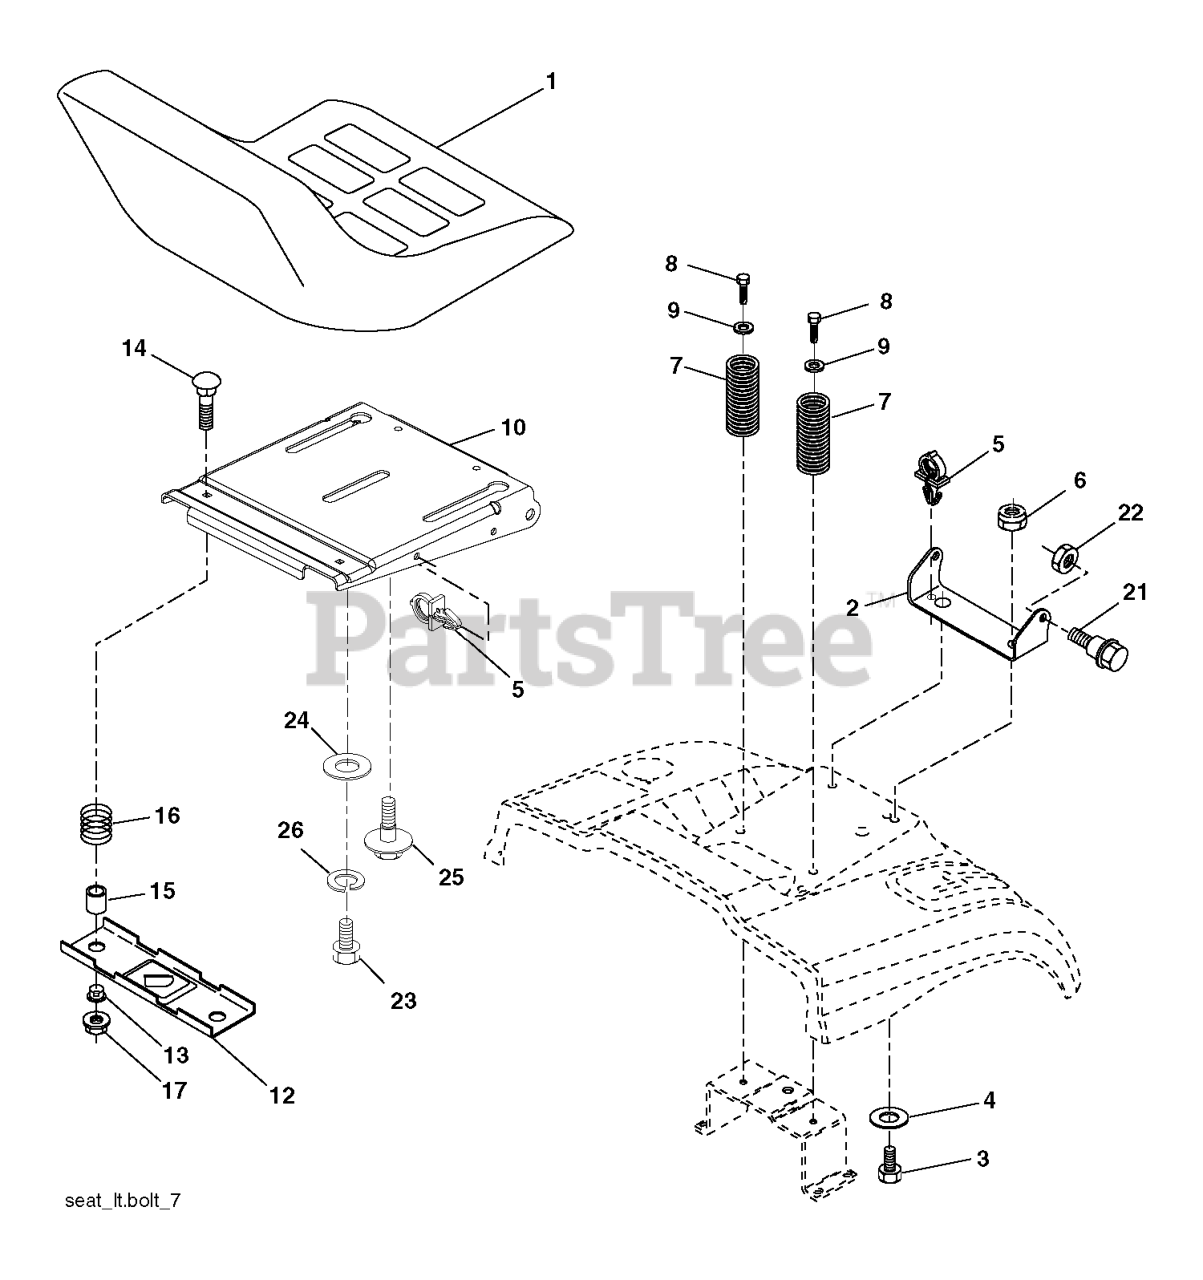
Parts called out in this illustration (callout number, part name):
1	SEAT.XG090.BLK.KB/BLT.NO-LOG
2	SEAT PIVOT BRKT
3	BOLT, HEX 3/8-16X1
6	NUT
7	SPRING COMPRESSION
8	SCREW 3/8-16X1
9	WASHER
10	PAN.ASM.SEAT.1SLOT
12	BRKT.MNTNG.SWITCH.SEAT.BLACK
14	BOLT.ROUND.HEAD.SQUARE.NECK
15	SPACER SPLIT 28X.96
17	NUT T
21	BOLT.SHOULDER.5/16-18
22	NUT.71038.31-18.HEX.NYLOCK
23	BOLT.HEX.BLACK
25	BOLT,SHOULD
26	LOCKWASHER
